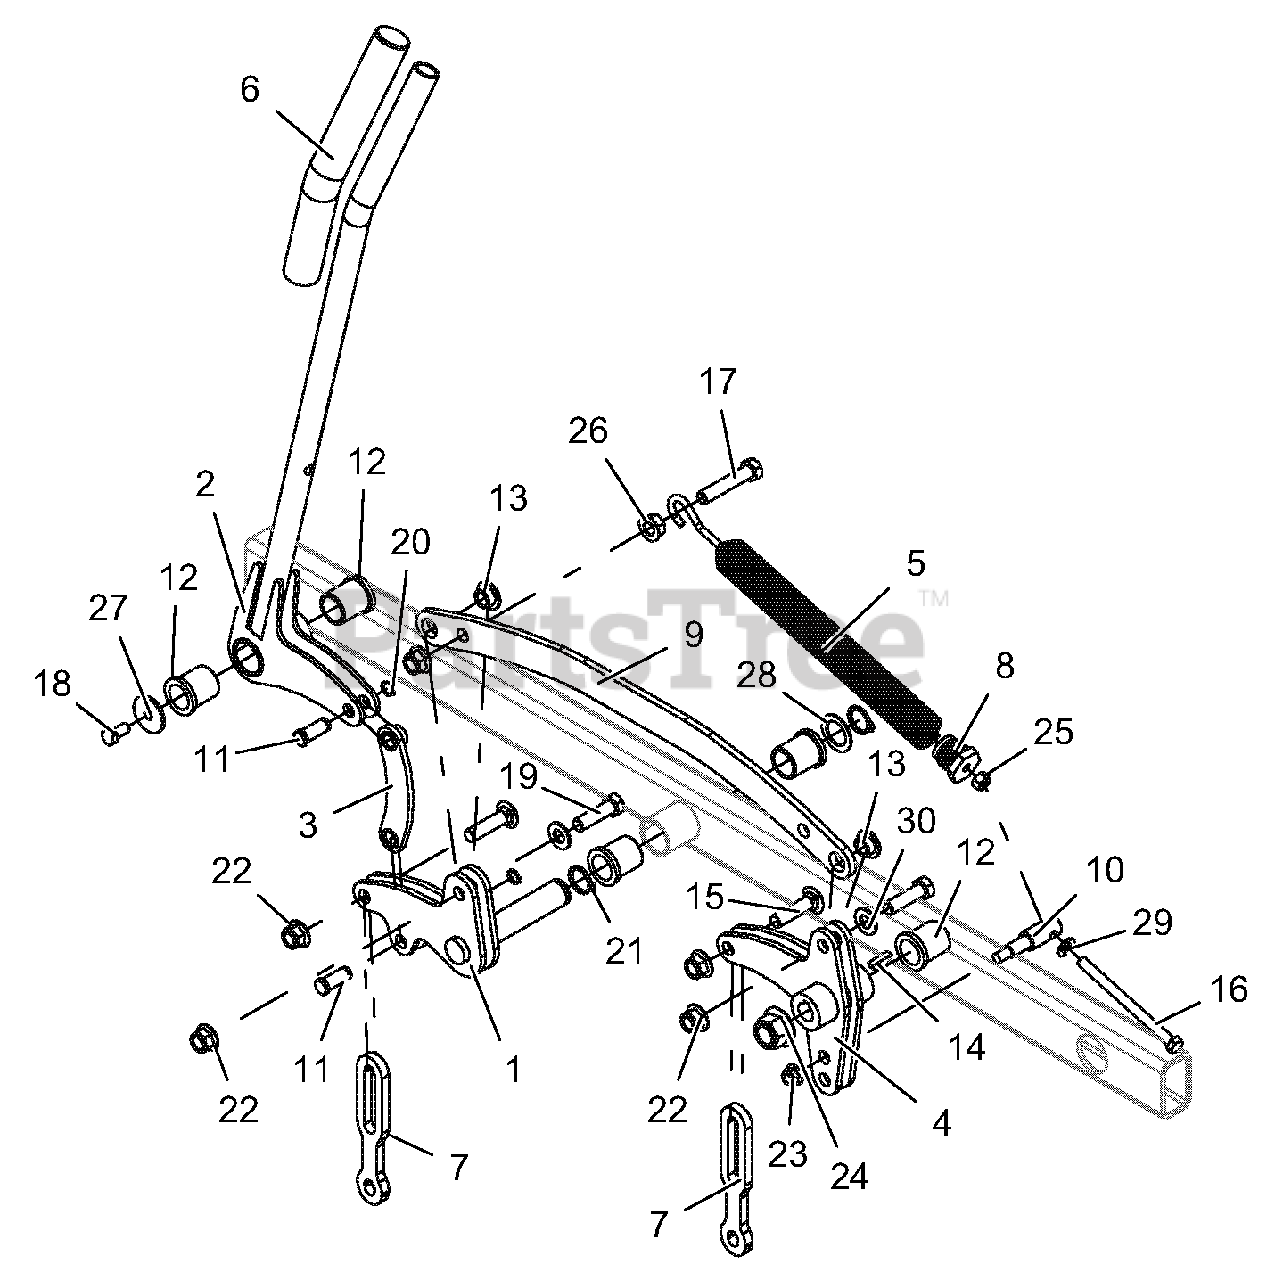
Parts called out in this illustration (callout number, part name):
1	WLDMT, DECK LIFT PROSTANCE
2	WLDMT, HAND LEVER - RED
3	WLDMT, DECK LIFT LINK
4	WLDMT, TAPERED HUB PROSTANCE (BLACK)
5	SPRG, DECK LIFT
6	GRIP, HANDLEBAR
7	LINK, DECK LIFT
8	PLUG, SPRG
9	ARM, DECK LIFT
10	TRUNION, DECK LIFT
11	PIN, CLEVIS .500 SNAP RING
12	BSHG-FLG 1.00 x 1.25 x 1.5 x 1.5
13	BSHG, FLANGE .515 x .750 x .420 x 1.12
14	KEY, WDRF .25 x 1.00 HRD #15
15	BLT-RDHDSQNK .50-13 x 2.00 G5 Y
16	BLT-HEX .38-16 x 5.00 GR5 YWZC
17	BLT-HEX .50-13 x 2.50 GR5 YWZC
18	BLT-HEX .38-16 x .75 GR5 YWZC
19	BLT-HEX .50-13 x 1.75 GR5 YWZC
20	RG-RTNG-EXT .500 x .050
21	RG-RTNG-EXT 1.00 x .078
22	NUT-LK-NYL-FLG .50-13 YWZC
23	NUT-LK-NYL-FLG .38-16 YWZC
24	NUT-LK-NYL-FLG .75-10 YWZC
25	NUT-HEX .38-16 YWZC
26	NUT .50-13 WIZ FLANGE
27	WSHR-FL-STL .380 x 1.50 x .125 YWZC
28	WSHR-FL-STL 1.010 x 1.505 x .062 YWZC
29	WSHR-FL-STL .406 x .812 x .065 YWZ
30	WSHR-FL-STL .531 x 1.06 x .095 YWZC
